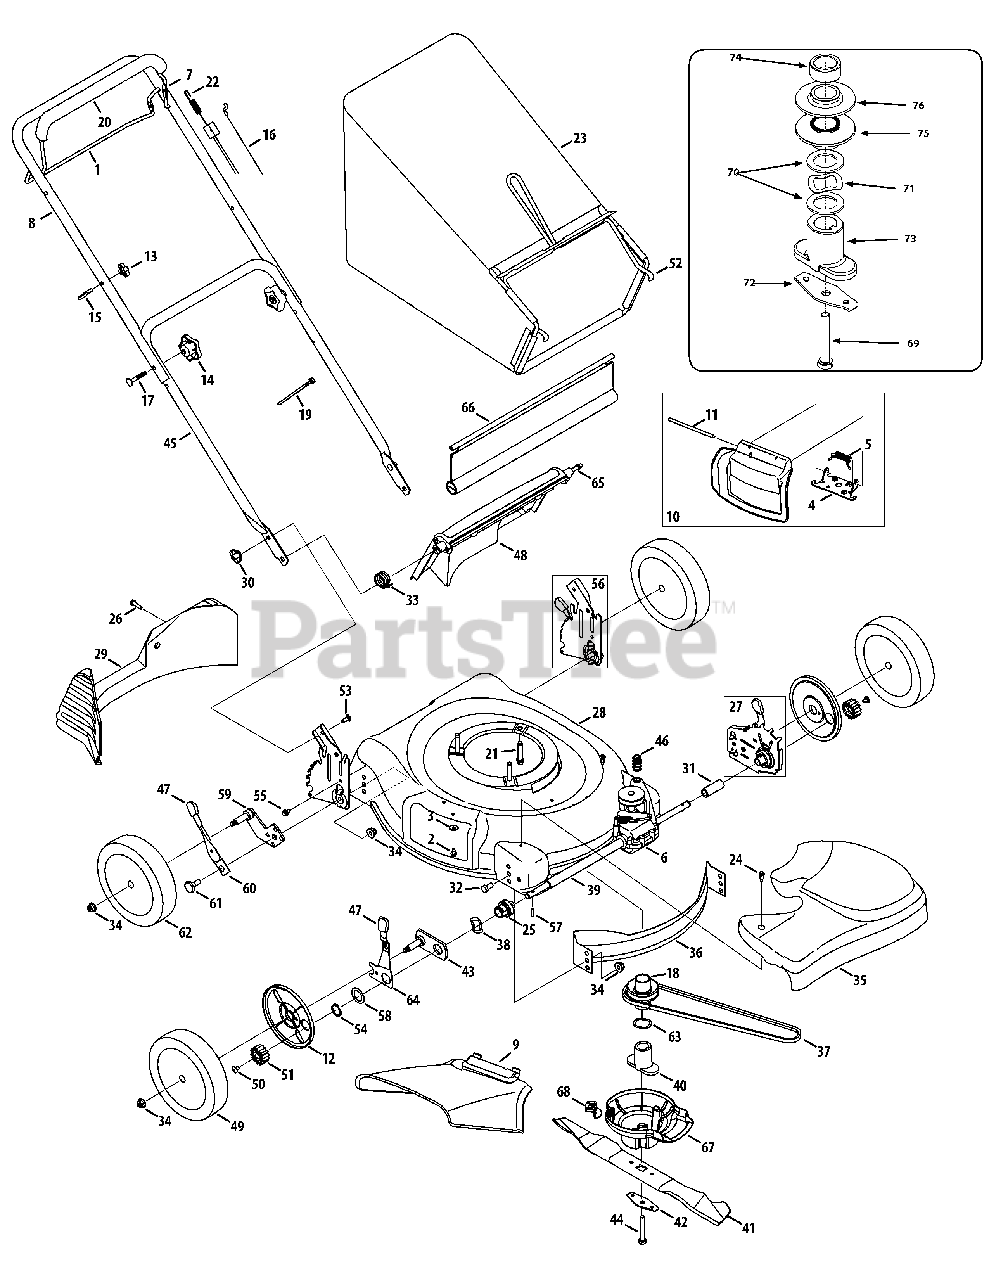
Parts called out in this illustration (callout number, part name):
1	Drive Control
2	TT Screw 1/4-20 x 0.5
3	Bell Washer.265 x 0.75
4	Deflector Chute Adapter
5	Torsion Spring
6	Transmission Assembly
7	Blade Control
8	Upper Handle
9	Chute Deflector
10	Mulch Plug Complete
11	Hinge Pin
12	Wheel Dust Cap
13	Handle Knob
14	Star Knob
15	Eye Bolt
16	Control Cable
17	Carriage Bolt 5/16-18 x 2.0
18	Pulley Assembly, Drive
19	Cable Tie
20	Bail Cover
21	Self-Tapping Sems Screw
22	Drive Cable
23	Grass Bag
24	Shoulder Screw # 12 -24
25	Front Bearing Assembly
26	Screw, 1/4-15 x 1.000
27	Height Adjustment Ass’y - RH
27	Height Adjustment Ass’y - LH
29	Rear Baffle
30	Wing Nut
31	Slev. Spacer 1.4" Lg.
32	Hex Screw, 3/8-16 x.75
33	Torsion Spring - RH
34	Flange Lock Nut, 3/8-16
35	Transmission Cover
36	Front Baffle
37	V-Belt
38	Wave Washer
39	Sleeve Spacer 8.985" Lg.
40	Blade Adapter, 25mm
41	21" Mulching Blade
42	Blade Bell Support
43	Pivot Plate Assembly
44	Hex Screw 3/8-24 x 2.50
45	Lower Handle
46	Belt Tension Spring
47	Adjustment Knob
48	Rear Discharge Door
49	Front Wheel
50	Screw, 1/4-20 x .390
51	Gear 14T RH FWD
51	Gear 14T LH FWD
52	Grass Bag Frame
53	Carriage Bolt 1/4-20
54	Snap Ring
55	TT Scr. w/Washer 1/4-20 x.625
56	Handle Bracket Assembly - RH
56	Handle Bracket Assembly - LH
57	Dowel Pin
58	Washer
59	Pivot Arm Assembly - RH
59	Pivot Arm Assembly - LH
60	Rear Spring Lever
61	Shoulder Scr.500 Dia. x.434
62	Rear Wheel
63	Wave Washer
64	Front Lever - RH
64	Front Lever - LH
65	Pivot Rod
66	Rear Trailing Shield
67	Engine Baffle
68	Engine Baffle Bracket
69	Hex Cap Screw, 3/8-24, 2.50, Gr8
70	Flat Washer, 1.031 x1.620 x .095
71	Wave Washer, ,1.5 x 1.0 x .029
72	Blade Bell Spacer
73	Blade Adapter, 25mm x 2.15 w/Star
74	Sleeve Spacer, 25mm x 1.375 x .620
75	Half Pulley, Keyed, 25mm ID
76	Half Pulley, Upper, 25mm ID
